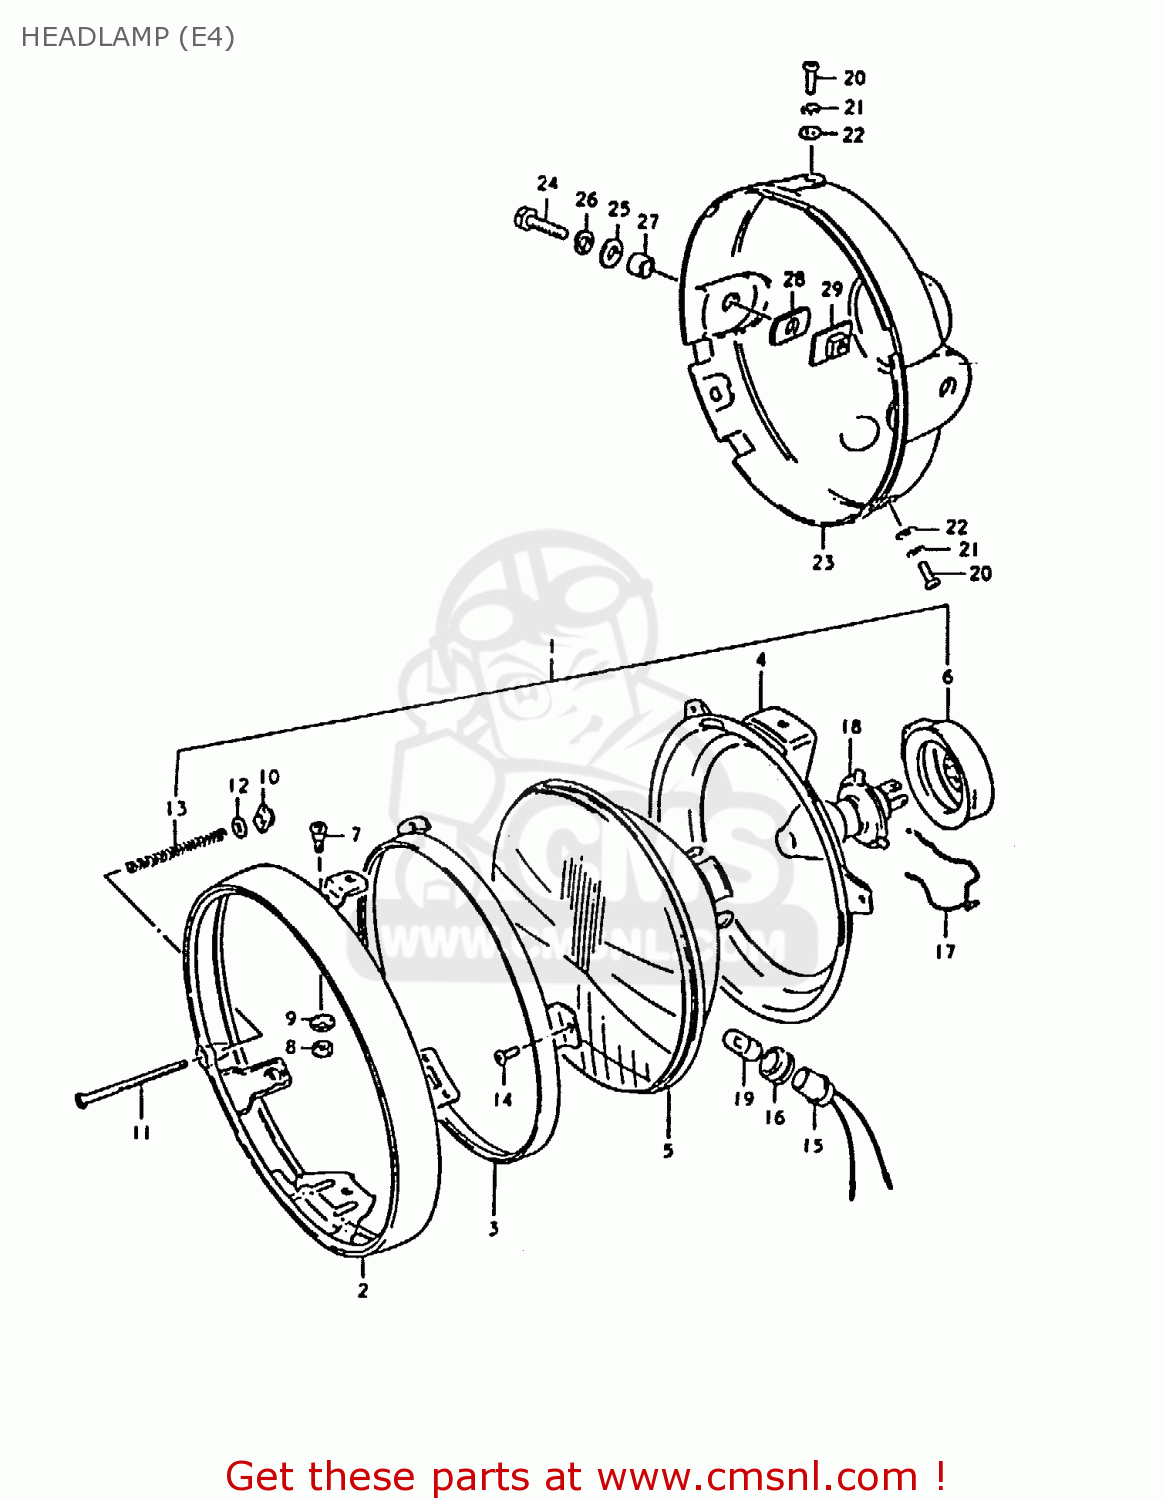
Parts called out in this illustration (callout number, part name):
1	HEADLAMP ASSY
2	RIM
3	RETAINER
4	RING,HEADLAMP UNIT
5	UNIT,HEAD LAMP
6	COVER,HEADLAMP SOCKET
7	SCREW
8	NUT,ADJUSTING
9	SPACER
10	NUT
11	SCREW,HEADLAMP ADJUST
12	WASHER
13	SPRING,HEADLAMP ADJUST
14	SCREW
15	SOCKET
16	JOINT,RUBBER
17	CLAMP,HEADLAMP SOCKET
18	BULB (12V, 60/55W, H4)
19	BULB(12V4W)
20	SCREW
21	WASHER,LOCK
22	WASHER
23	HOUSING,HEADLAMP(BLACK)
24	BOLT
25	WASHER
26	LOCK WASHER
27	SPACER (8.8X12X7)
28	CUSHION
29	PLATE,HEADLAMP HOUSING
